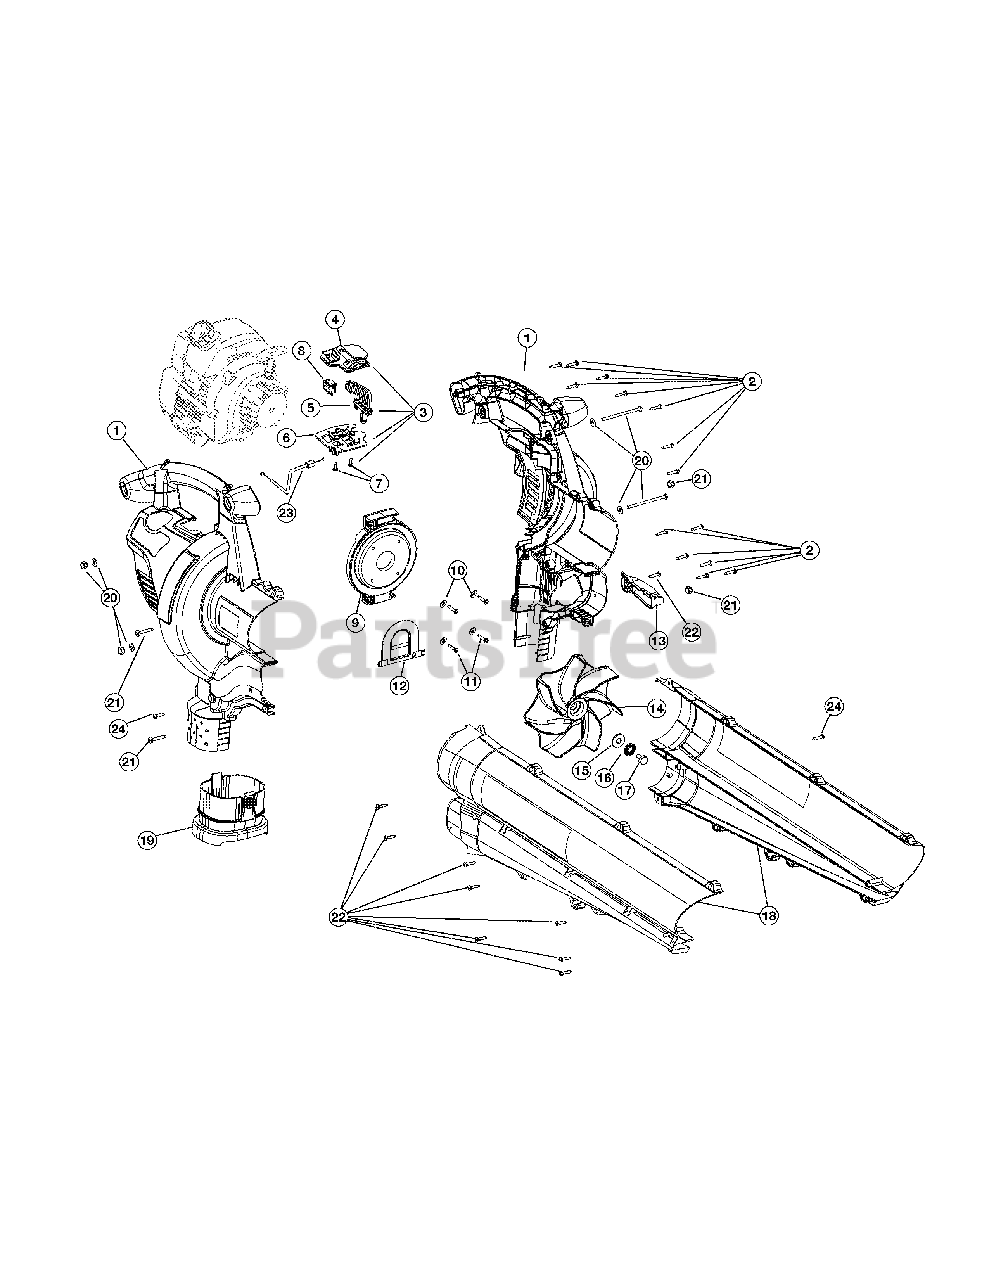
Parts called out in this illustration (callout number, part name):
1	Engine Cover Assembly
2	Cover Screw
3	Throttle Control Assembly
4	Upper Throttle Control Plate
5	Throttle Control Lever
6	Lower Throttle Control Plate
7	Screw, Plastic
8	Rocker Switch Assembly
9	Engine Mounting Plate
12	Mode Control Flapper
13	Mode Control Lever
14	Impeller Blade
15	Washer
16	Lock Washer
18	Blower/Vac Tube Assembly
19	Vacumm Bag Adapter
20	Mounting Plate Hardware
21	Blower/Vac Tube Mounting Hardware
23	Throttle Cable
